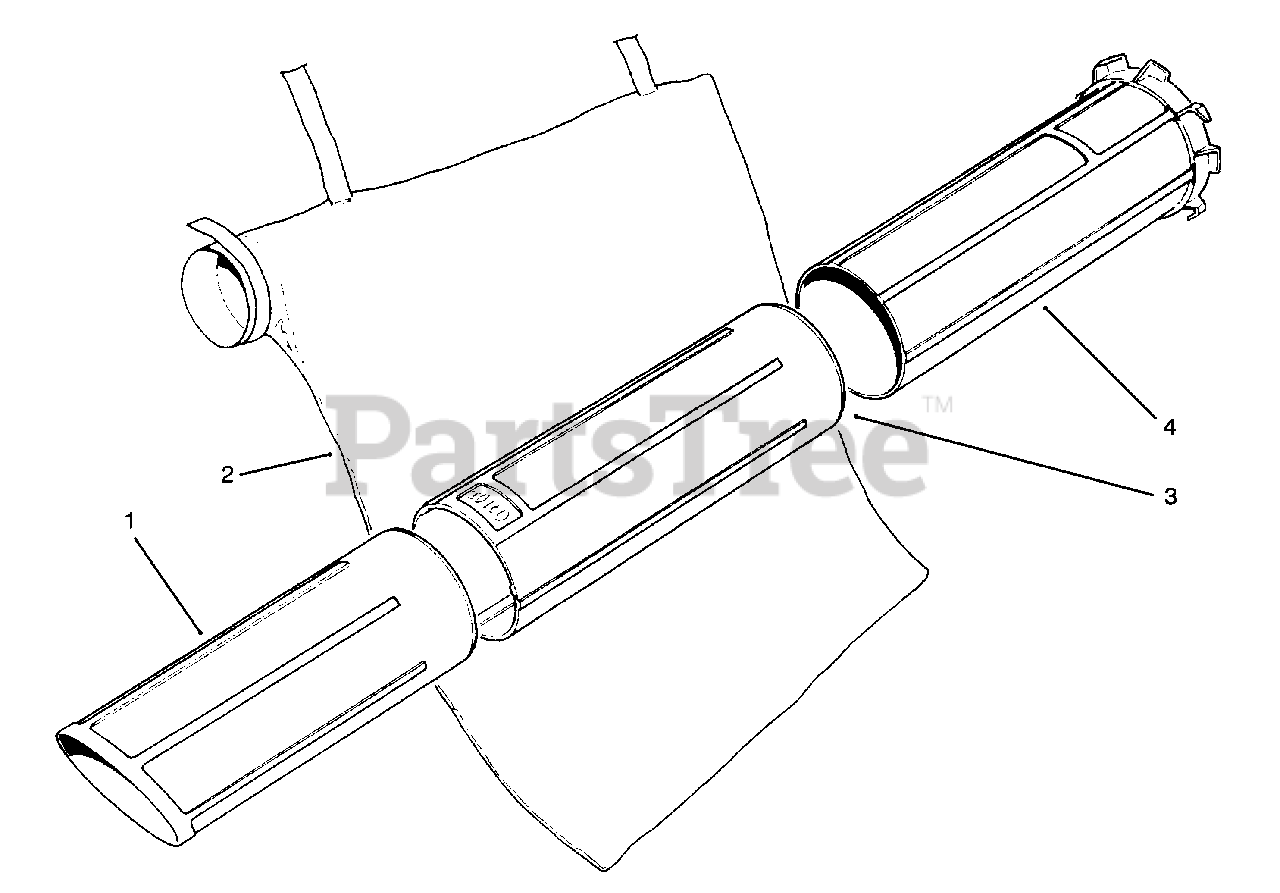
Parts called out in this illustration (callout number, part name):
1	Tube-Vacuum, Lower
2	Bag-Vacuum
3	Tube-Vacuum, Middle
4	Tube-Vacuum, Upper
